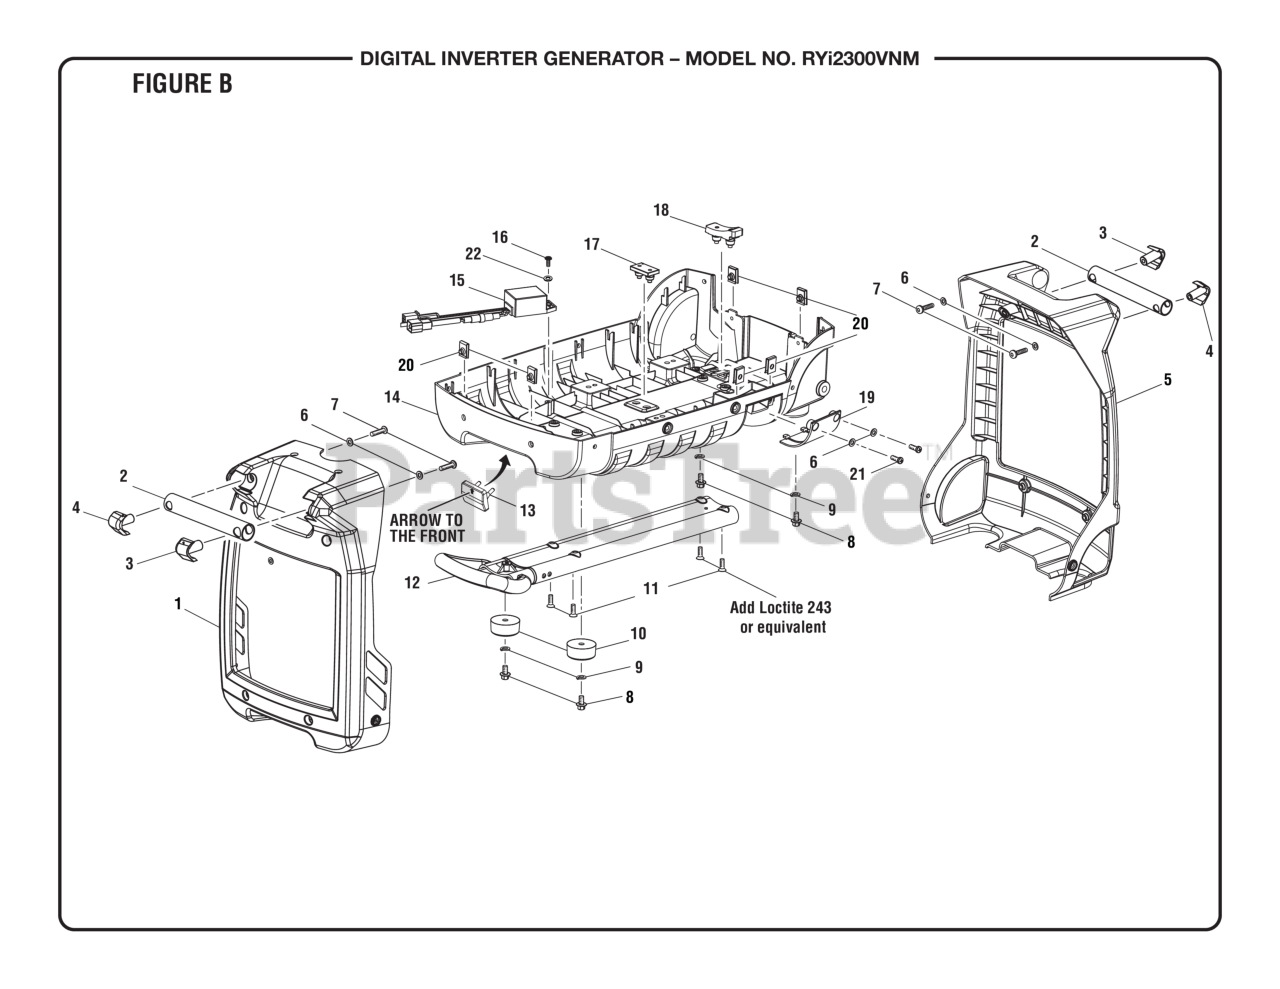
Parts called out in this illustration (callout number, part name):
1	Front Cover
2	Handle Tube
3	Handle Cap (Right)
4	Handle Cap (Left)
5	Back Cover
6	Washer (ID5.3 x OD10 x 1t)
7	Screw (M5 x 20 mm, Button Soc. Hd.)
8	Bolt (M6 x 12 mm, Hex Hd.)
9	Lock Washer (1/4 in.)
10	Isolator Foot
11	Screw (M5 x 16 mm, Flat Hd.)
12	Handle Assembly
13	Handle Bumper
14	Bottom Base
15	Regulator (AC to DC)
16	Screw (M4 x 16 mm, T20 Torx Socket Pan Hd.)
17	Engine Support Isolator (Front)
18	Engine Support Isolator (Back)
19	Oil Drain Door
20	U-Clip (M5)
21	Screw (M5 x 12 mm, Phillips Pan Hd)
22	Washer (ID5.3 x OD10 x 1t)
